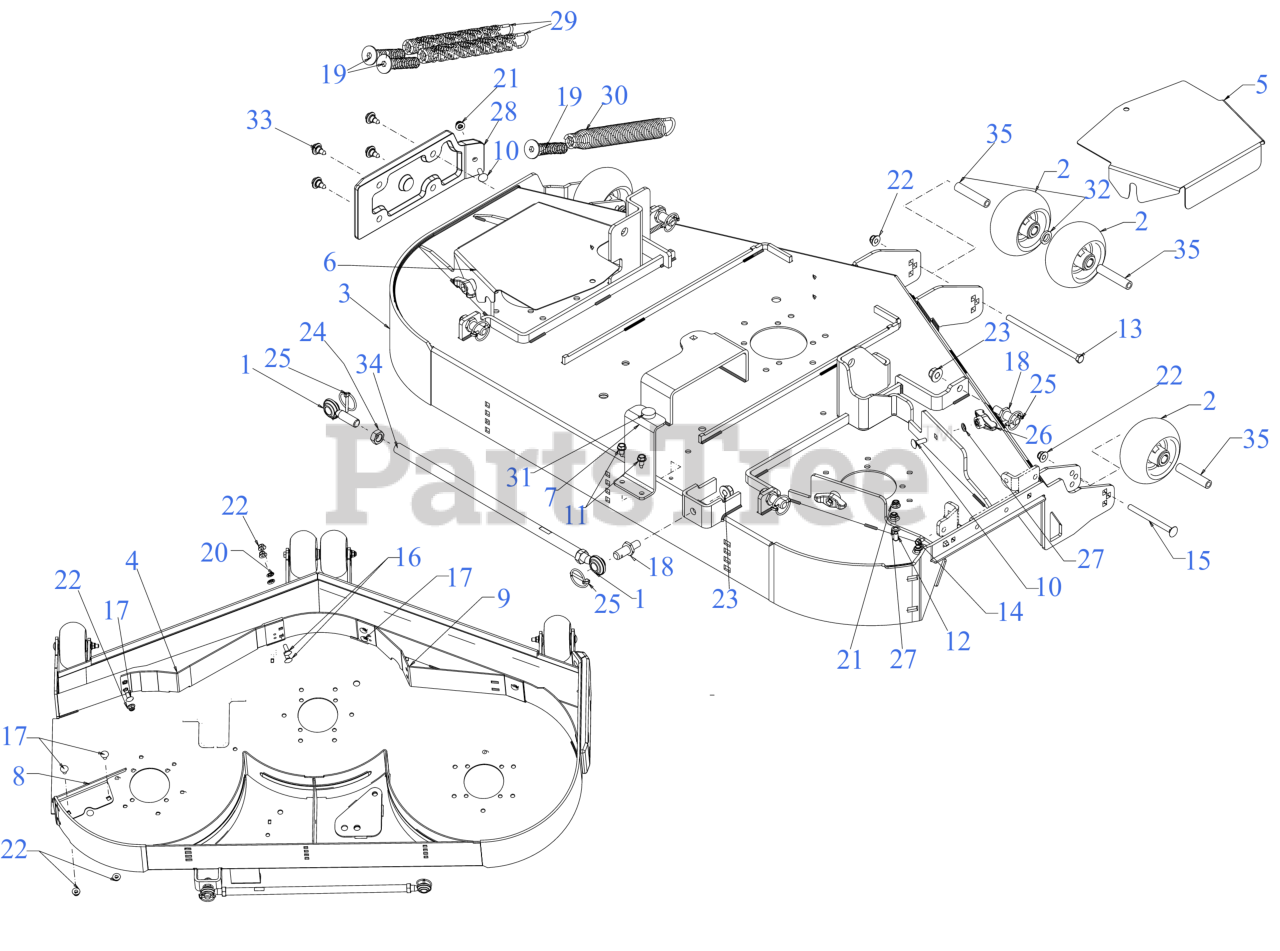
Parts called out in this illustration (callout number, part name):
1	MALE ROD END
2	5" DIA DECK WHEEL COMPLETE
3	54" FAB DECK SHELL
4	DECK BAFFLE
5	BELT COVER (RH)
6	BELT COVER (LH)
7	DECK STOP BRACKET
8	CHUTE BAFFLE
9	BAFFLE
10	CARRIAGE BOLT 5/16-18 x 1.00
11	SCREW 5/16-18 x .750
12	CARRIAGE BOLT 5/16-18 x .75
13	SCREW 3/8-16 x 7.25 GR5
14	SCREW 1/4-20 X.500
15	CARRIAGE BOLT 3/8-16 x 4.25 GR5
16	CARRIAGE BOLT 3/8-16 x 1.00 GR5
17	CARRIAGE BOLT 3/8-16 x .75
19	SPRING INSERT SCREW
21	FLANGE LOCK NUT 5/16-18
24	HEX JAM NUT 5/8-18
25	LYNCH PIN .1875
26	WING KNOB 5/16-18
28	DECK SKID PLATE (LH)
29	EXTENTION SPRING 1.20 x 11.35
30	EXTENSION SPRING 1.44 OD x 11.36
31	RUBBER BUMPER 1.000 x .313
32	FLAT WASHER .632X1.00X.16
33	SHOULDER SCREW .43X.29X5/16-18 TT
34	TUBE .565 X .750 X 18.75"LG
35	WHEEL SPACER .38ID x 3.04LG
